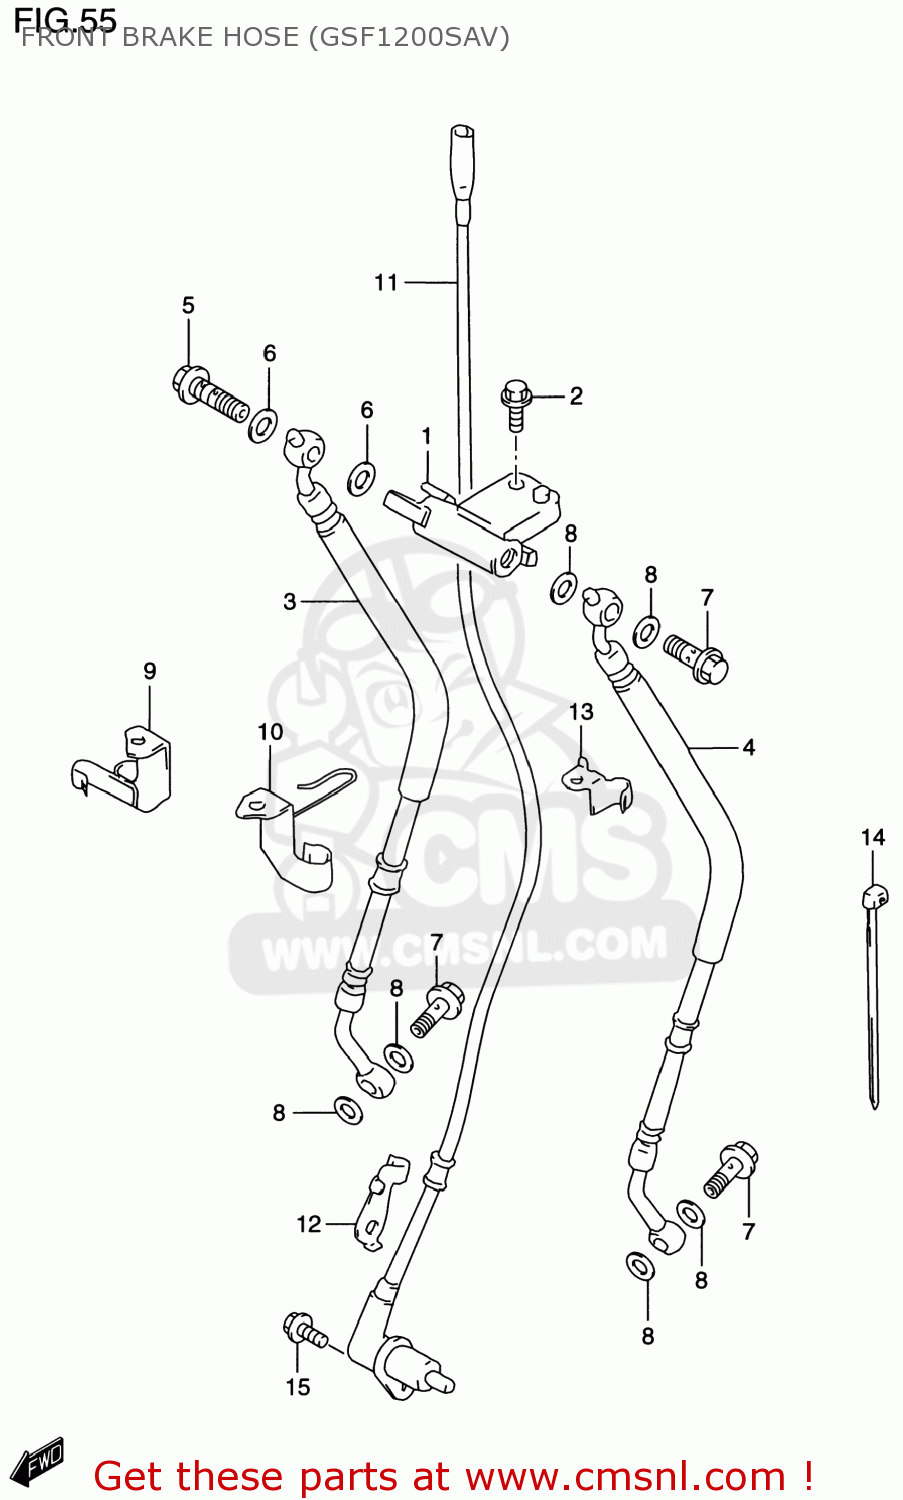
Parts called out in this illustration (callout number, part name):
1	JOINT,BRAKE HOSE
2	BOLT
3	HOSE,FR BRAKE NO.2,R
4	HOSE,FR BRAKE NO.2,L
5	BOLT UNION
6	WASHER(10X15X1.5)
7	BOLT UNION
8	WASHER(10X15X1.5)
9	CLAMP,FR BRAKE HOSE,R
10	CLAMP,FR BRAKE HOSE,L
11	SENSOR,FR WHEEL ABS
12	CLAMP,ABS SENSOR FORK
13	CLAMP,ABS SENSOR FR JOINT
14	CLAMP(L:145)
15	BOLT
